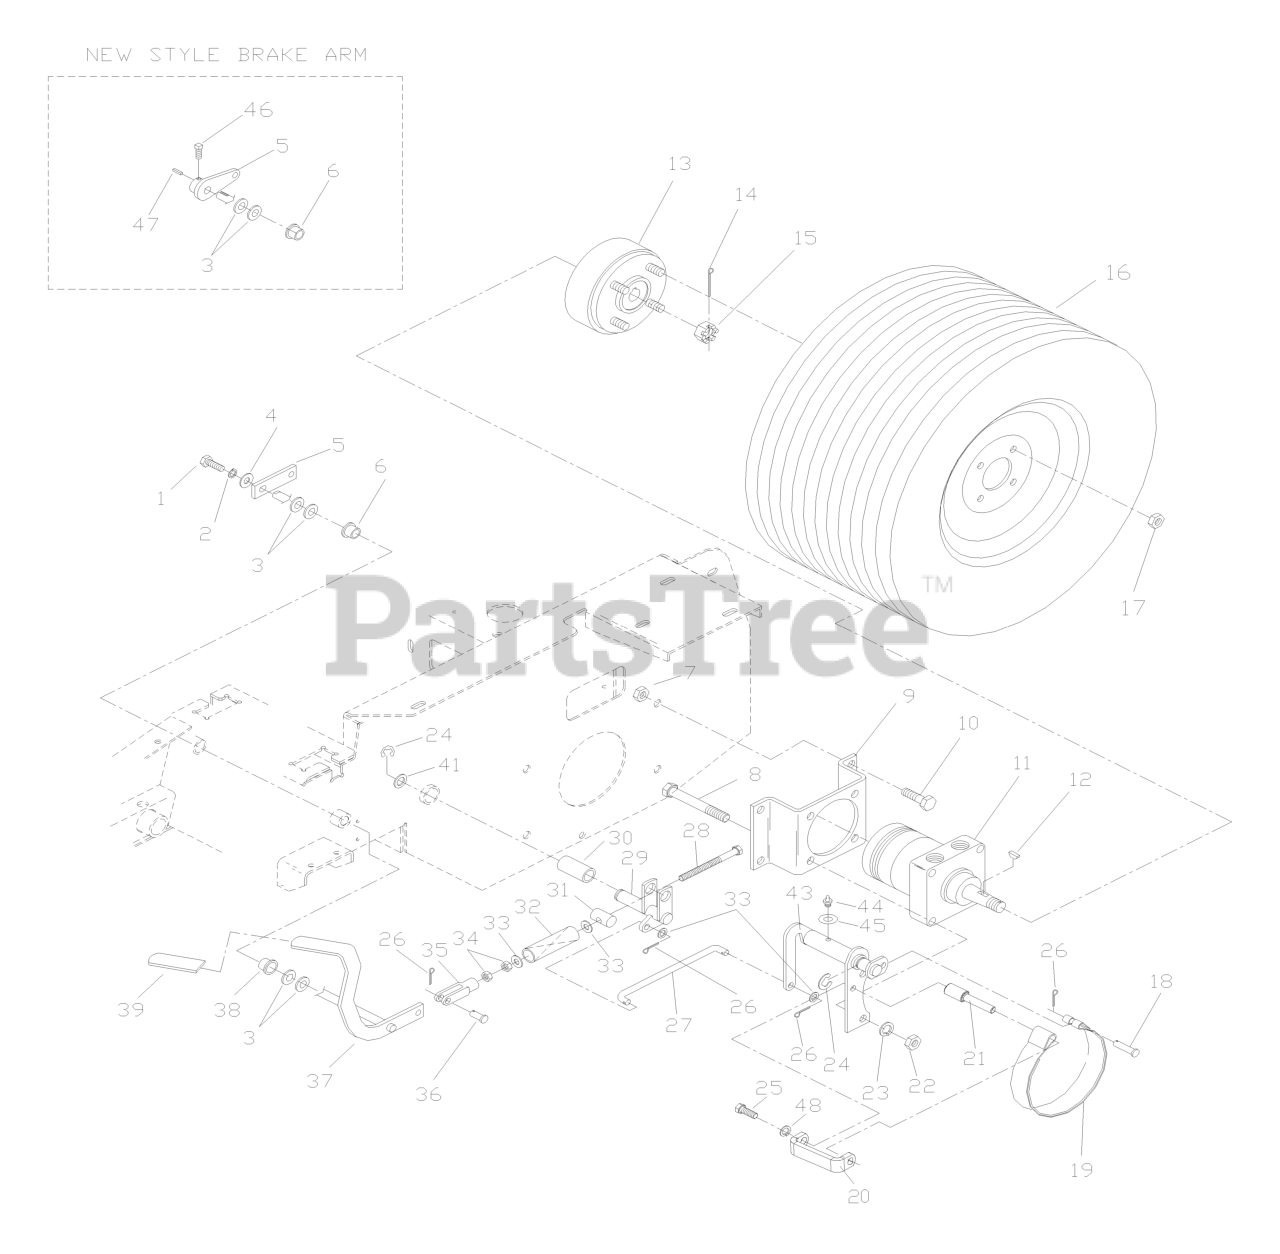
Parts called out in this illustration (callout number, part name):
1	HCS 1/4C X 3/4 HCS
2	LOCKWASHER 1/4"
3	WASHER, 7/16 DISC SPRING
4	WASHER 1/4 FLAT
5	ARM, PARK BRAKE
5	BRAKE ARM WELDMENT
7	NUT 1/2-13 HEX NYLOC ZD
8	HCS 1/2C X 2 3/4
9	MOTOR STANDOFF - PAINTED
10	HCS 1/2C X 1 1/4 SERRATED HEAD
11	MB WHEEL MOTOR
12	WOODRUFF KEY
13	HUB W/BRAKE DRUM
14	COTTER PIN
15	CASTLE-NUT
16	WHEEL/TIRE.ASM.24X12-12.SILVER
16	REAR TIRE/WHEEL ASM
16	TIRE.24X12-12.TURF.MASTER
16	12"RIM 2.5" NEG OFFSET 8.5" W
16	RIM 0 OFFSET 8.5" WIDE
16	VALVE STEM TR-412
17	LUG NUT 1/2F
18	CLEVIS PIN, 3/8 X 1 1/2
19	BRAKE BAND
20	BRAKE SUPPORT BRACKET
20	HCS 3/8 X 3 GD.8
21	BRAKE BAND PIVOT
22	NUT HEX 1/2
23	WASHER 1/2" SPLIT LOCK
24	E RING 3/4
25	HEX BOLT 3/8 X 1"
25	NUT 3/8C CENTERBLOCK
26	RP_COTTER PIN 1/8 X 3/4
27	BRAKE LINKAGE, LT.
27	BRAKE LINKAGE, RT.
28	HCS 3/8F X SPECIAL
30	BRONZE BEARING
31	TRUNION PIN
33	WASHER 3/8 SAE FLAT
35	YOKE-3/8-24 PLTD
36	CLEVIS PIN 3/8 X 1 1/8
37	BRAKE LEVER WIDMT
39	GRIP, PARK BRAKE
43	LT.BRAKE WLDMT
43	RT.BRAKE WLDMT
44	ZERK
46	SCREW 5/16C X 5/8 SQ HEAD
48	SLW 3/8 STD
